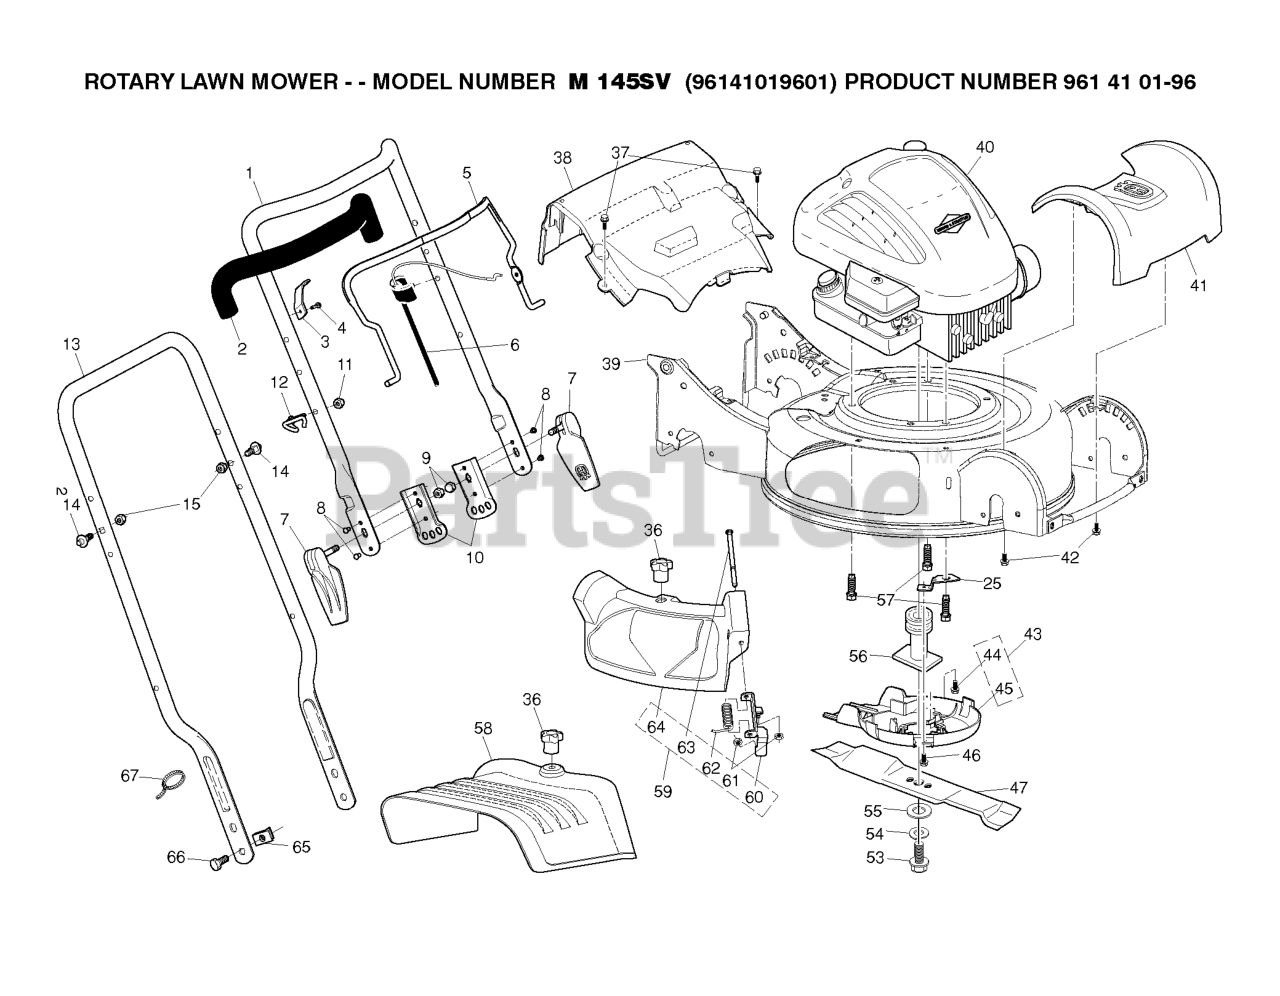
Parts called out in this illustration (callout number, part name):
1	HANDLE.ASM.UP.W/ADJ.BKT
2	GRIP.HANDLE.FOAM.WIDE.(1 SIDE)
3	BRACKET.UPSTOP.RT
5	BAIL.CONTROL.MZR.BS.ORANGE
6	CONTROL.ZONE.ASM
7	QUICK.ASM.RELEASE.BLACK
9	Locknut, Hex 1/4-20
10	BRACKET.ADJ.3POS.GREY
11	NUT
12	RB GUIDE.ROPE.STD.BLK.ZIN WSL
14	STUD.QUICK.ADJUST
15	NUT.LOCK.5/16-18
25	BRACKET
36	KNOB.MULCH.DOOR
37	SCREW, HEX WASHER HEAD
42	SCREW.HWH.13-16-5.8.BZP
44	HINGE SCREW
46	SCREW.HEX.WSH
53	BOLT.HD.HEAD.3/8-24X2.50 (2 2)
54	LOCKWASHER
55	WASHER,HARDEN
57	BOLT 3/8-16X1-1/8
61	NUT.HEX.FLANGE.1/4
62	SPRING.MULCH.DOOR
63	ROD.HINGE.1/4"3.82"
64	DOOR.MULCH.GREY
67	TIE GUIDE
